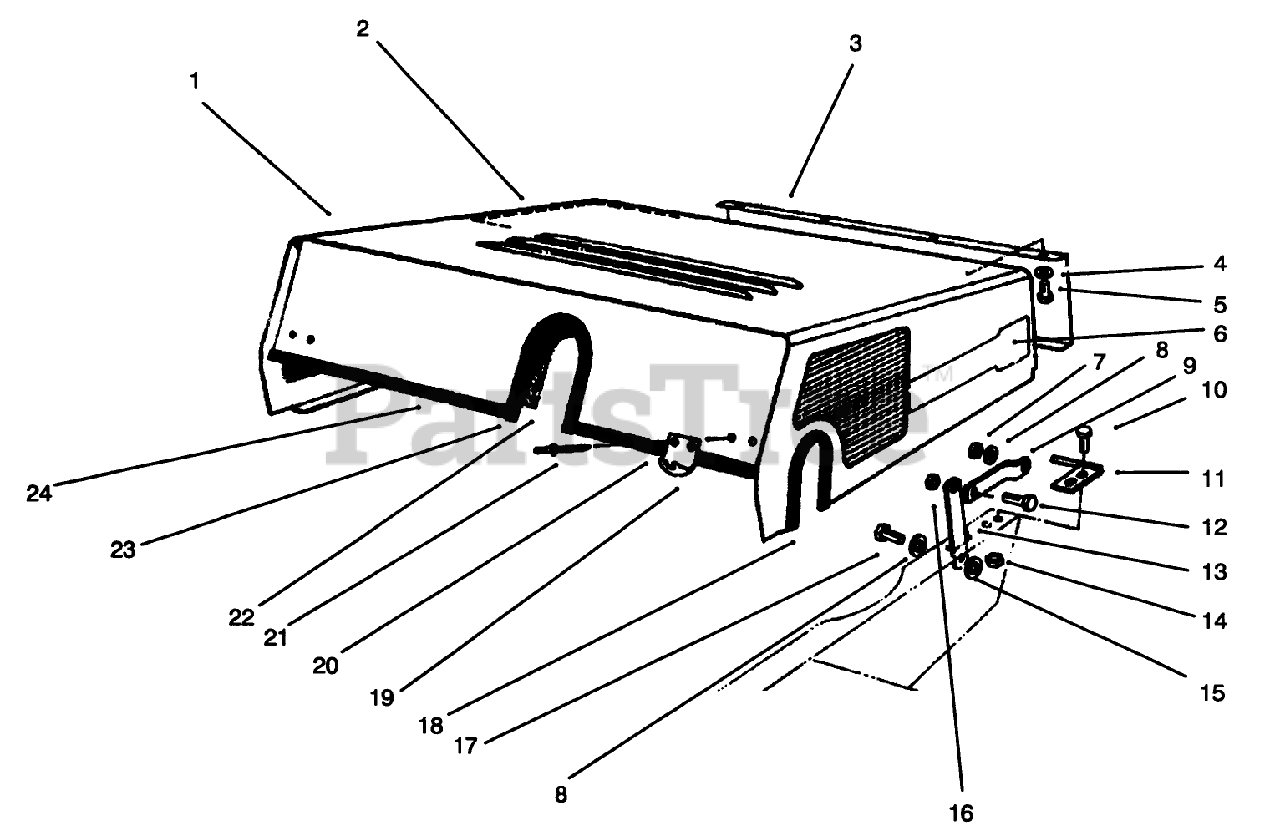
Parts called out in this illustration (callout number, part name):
1	HOOD IN CARTON
2	REAR HOOD FOAM STRIP
3	Grille-Rear Panel
4	WASHER-FLAT
5	Screw
6	GM 220 DECAL
7	NUT-HF
8	WASHER-SPRING
9	Link Hood
10	SCREW-HHF
11	PivotPin L.H.
12	SCREW-HH
13	Tie Hood
14	NUT-HF
15	WASHER-FLAT
16	SCREW-SHOULDER
17	NUT-HEX
18	HOOD TRIM
19	KEEPER
20	HOOD TRIM
21	RIVET
22	FRT HOOD FOAM STRIP
23	HOOD TRIM
24	TRIM-HOOD
